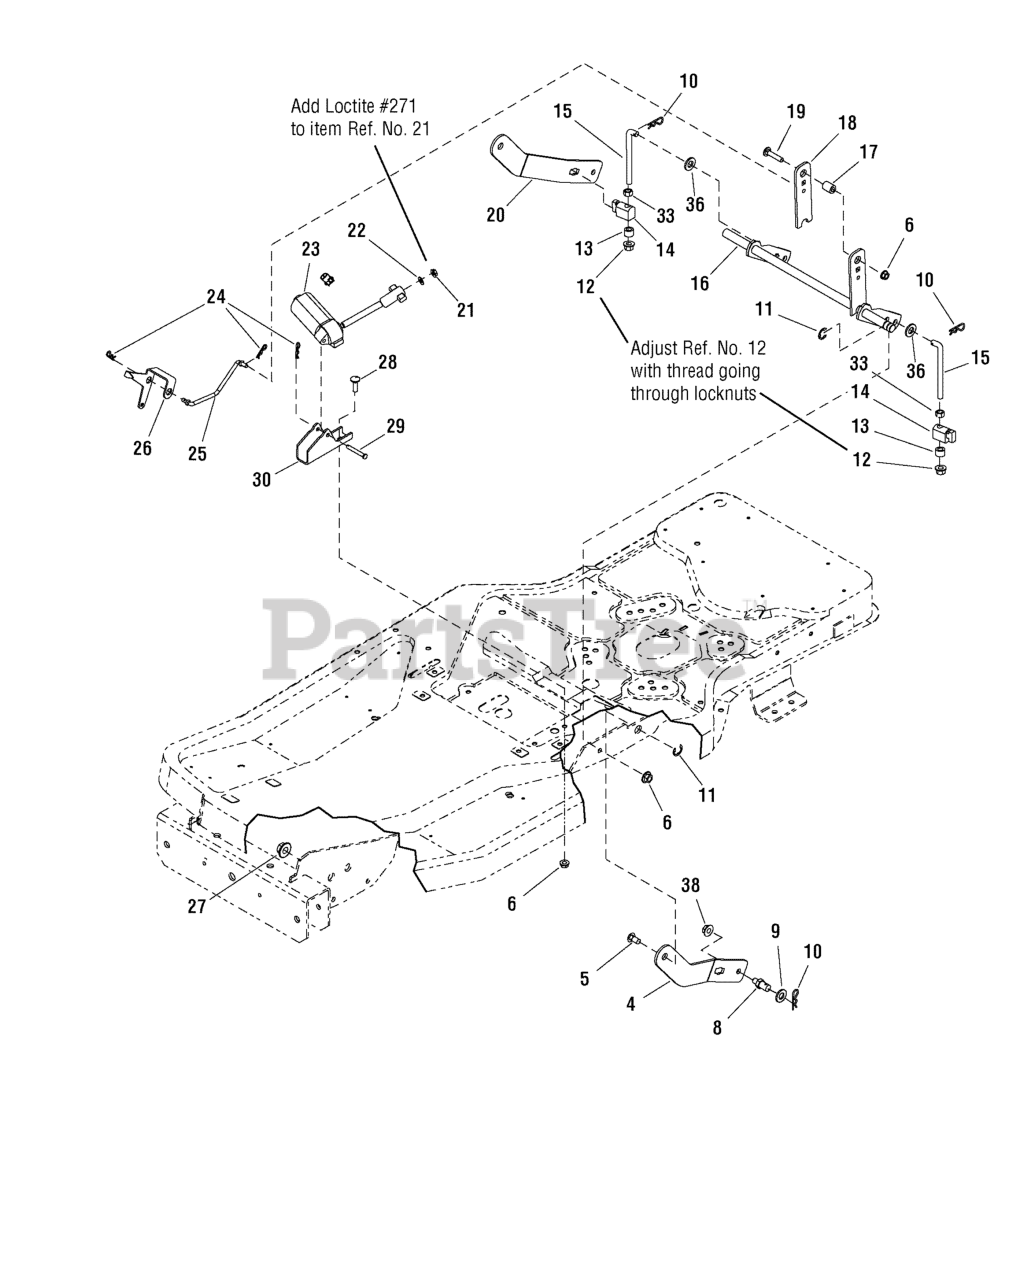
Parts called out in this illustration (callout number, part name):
4	ARM, Mower Lift L.H.
5	BOLT, Shoulder
6	NUT, Hex Whiz Lock Flange, 5/16-18
8	PIN, Threaded Shoulder
9	WASHER, 1/2"
10	CLIP, Hair Pin
11	RING, Klipring, 5/8"
12	NUT, Hex Flange, 3/8-16 ESNA
14	TRUNNION
15	ROD, Mower Lift 3/8-16 x 1 LG Thread
16	LIFT SHAFT ASSEMBLY
17	SPACER, Powdered Metal
18	ARM, Lift Trunnion
19	CARRIAGE BOLT, 5/16-18 x 1-1/2, G5
20	ARM, Mower Lift R.H.
21	NUT, Hex, 1/4-20 L.H. Thread
22	WASHER, 1/4"
23	MOTOR, Mini Actuator
24	PIN, Quick
25	ROD, Height of Cut Indicator
26	INDICATOR, Height of Cut
28	BOLT, Carriage, Short Neck, 5/16-18 x 1
29	PIN, Shear
30	BRACKET, Electric Motor Mount
33	NUT, Hex 3/8 - 16
36	WASHER, 3/8
38	NUT, Hex Two-Way Lock Flange, 3/8 - 16
